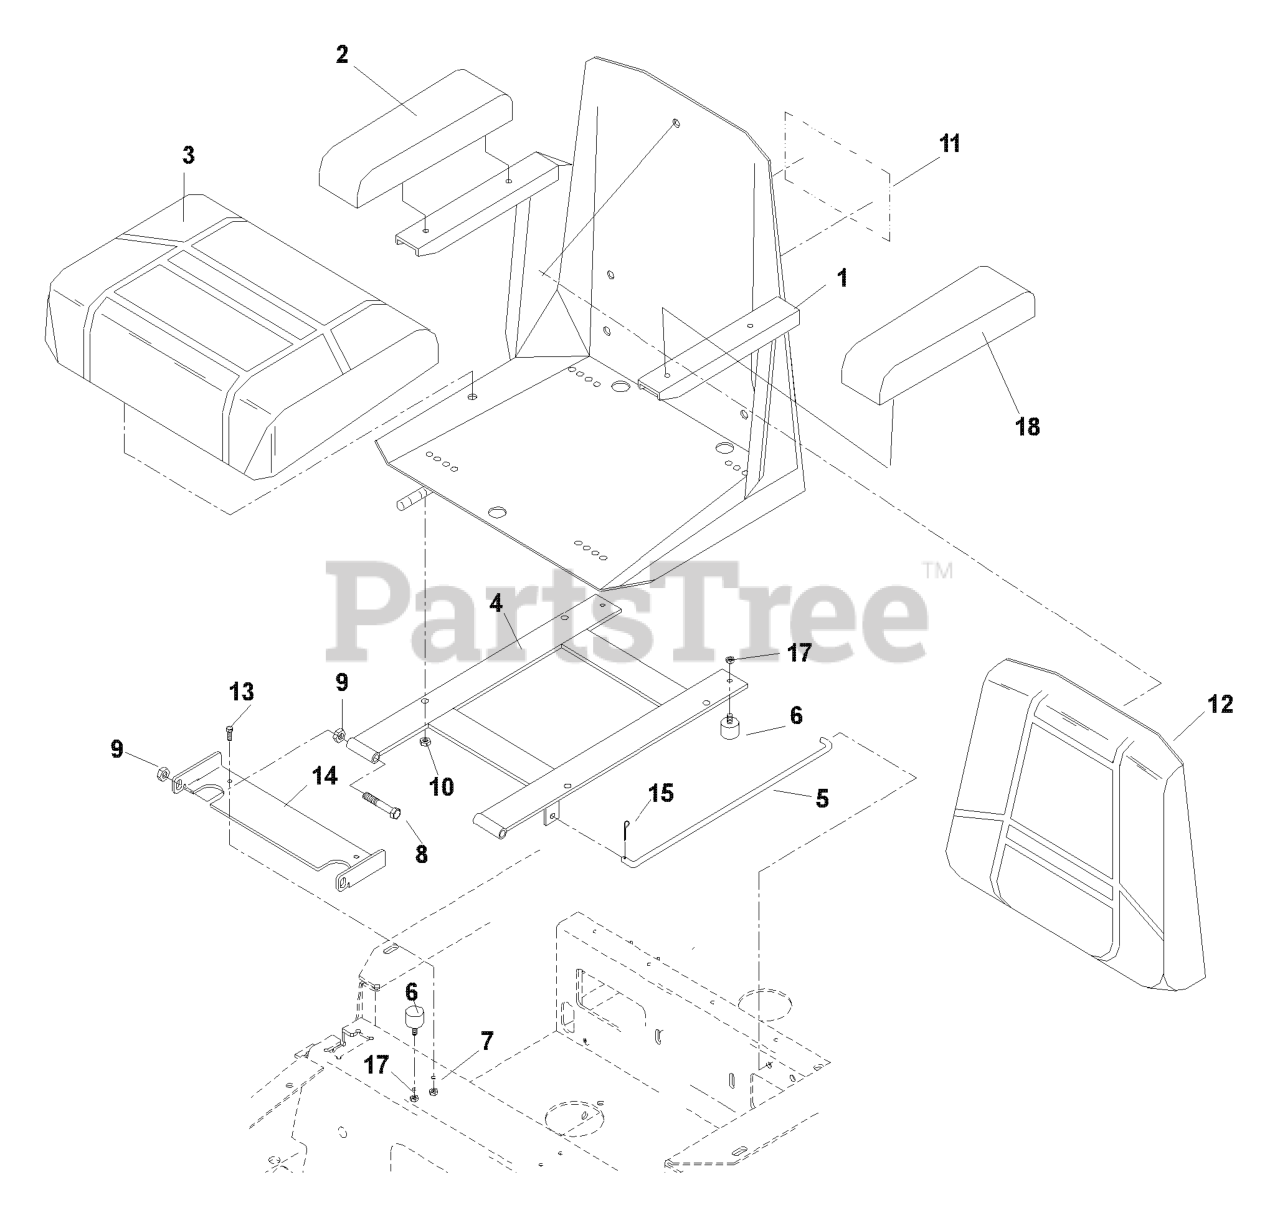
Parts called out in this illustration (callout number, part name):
1	SEAT COMPLETE
2	ARMREST KIT, RH
3	SEAT CUSHION KIT
4	SEAT MOUNT
6	STUD/PLATE MOUNT
7	NUT 1/4C CENTERLOCK
8	HCS 3/8C X 3
9	NUT 3/8C CENTERBLOCK
10	NUT 5/16 NYLOC
11	DECAL, CROWN H
12	BACK CUSHION KIT
13	HCS 1/4C X 3/4 HCS
14	SEAT BRKT W/DECAL
15	RP_COTTER PIN 1/8 X 3/4
17	NUT.1/4-20.HEX.NYLOC.ZD
18	ARMREST KIT, LH
